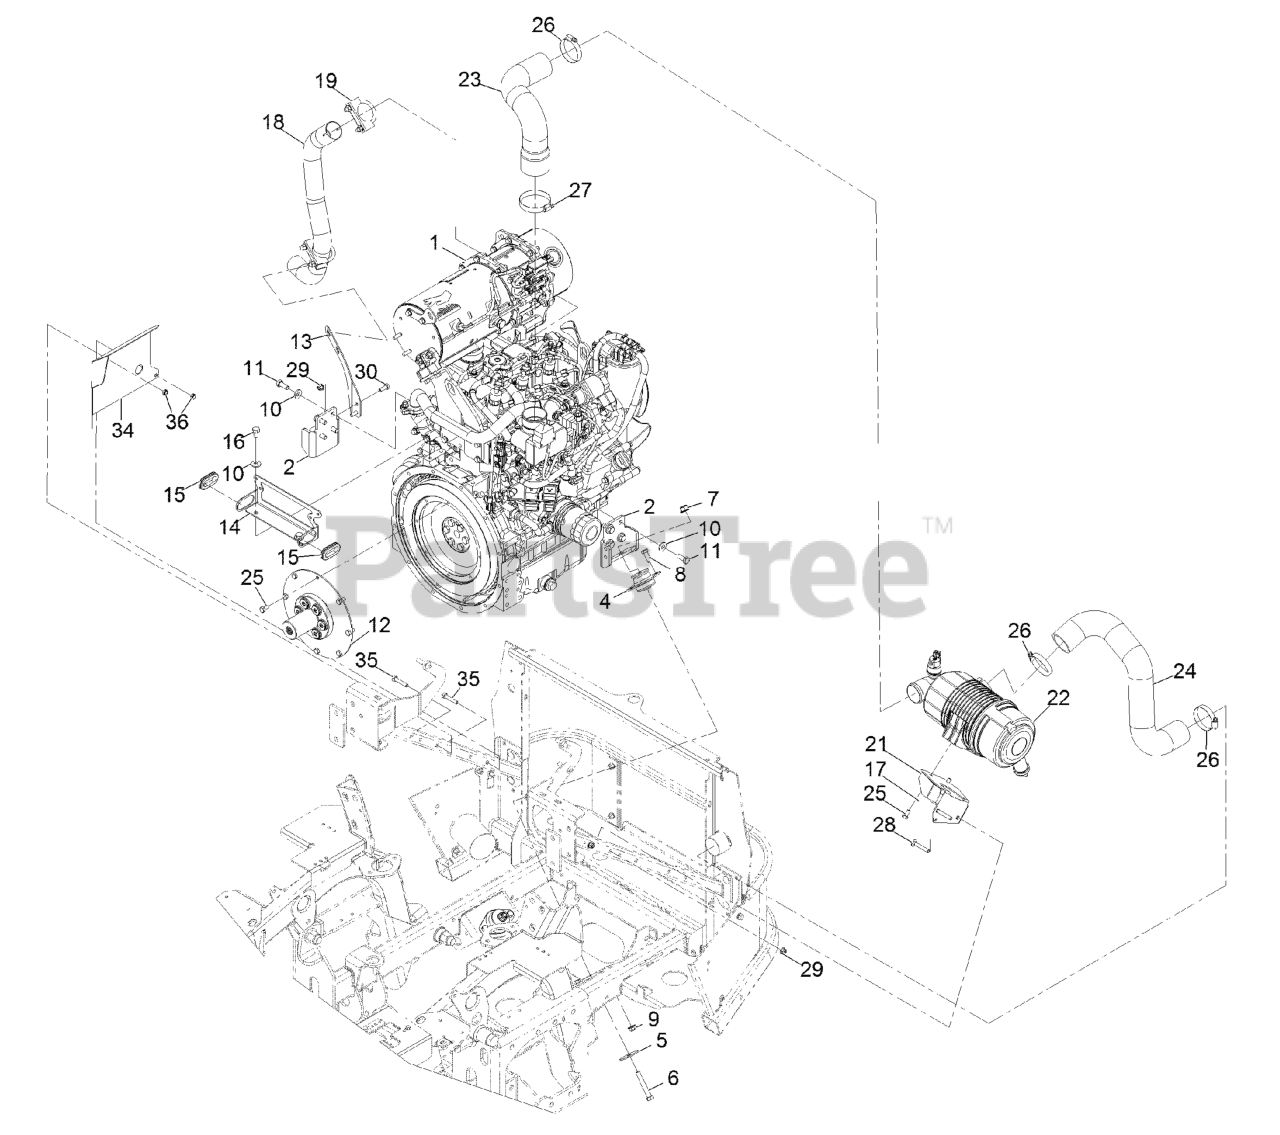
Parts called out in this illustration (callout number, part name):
1	ENGINE-YANMAR, 3TNV88C-DT
2	MOUNT-MOTOR, UPPER
5	WASHER-SNUBBING
6	SCREW-HH
7	NUT-HF, NI
8	SCREW-HH
9	NUT-HF, NI
10	WASHER-BELLEVILLE
11	SCREW-HH
12	COUPLING-FLYWHEEL
13	BRACKET-MOUNT
14	BRACKET-GUIDE
15	GROMMET-RUBBER
16	SCREW-HH
17	WASHER-BELLEVILLE
18	TUBE-EXHAUST
21	BRACKET-CLEANER, AIR
22	AIR CLEANER ASM
23	HOSE-AIR
24	HOSE-AIR
25	BOLT
26	CLAMP-HOSE
27	CLAMP-HOSE
28	BOLT-CARR
29	NUT-HF, NI
30	SCREW-HH
34	DEFLECTOR-AIR
35	SCREW-HH
36	NUT-LOCK, NI
